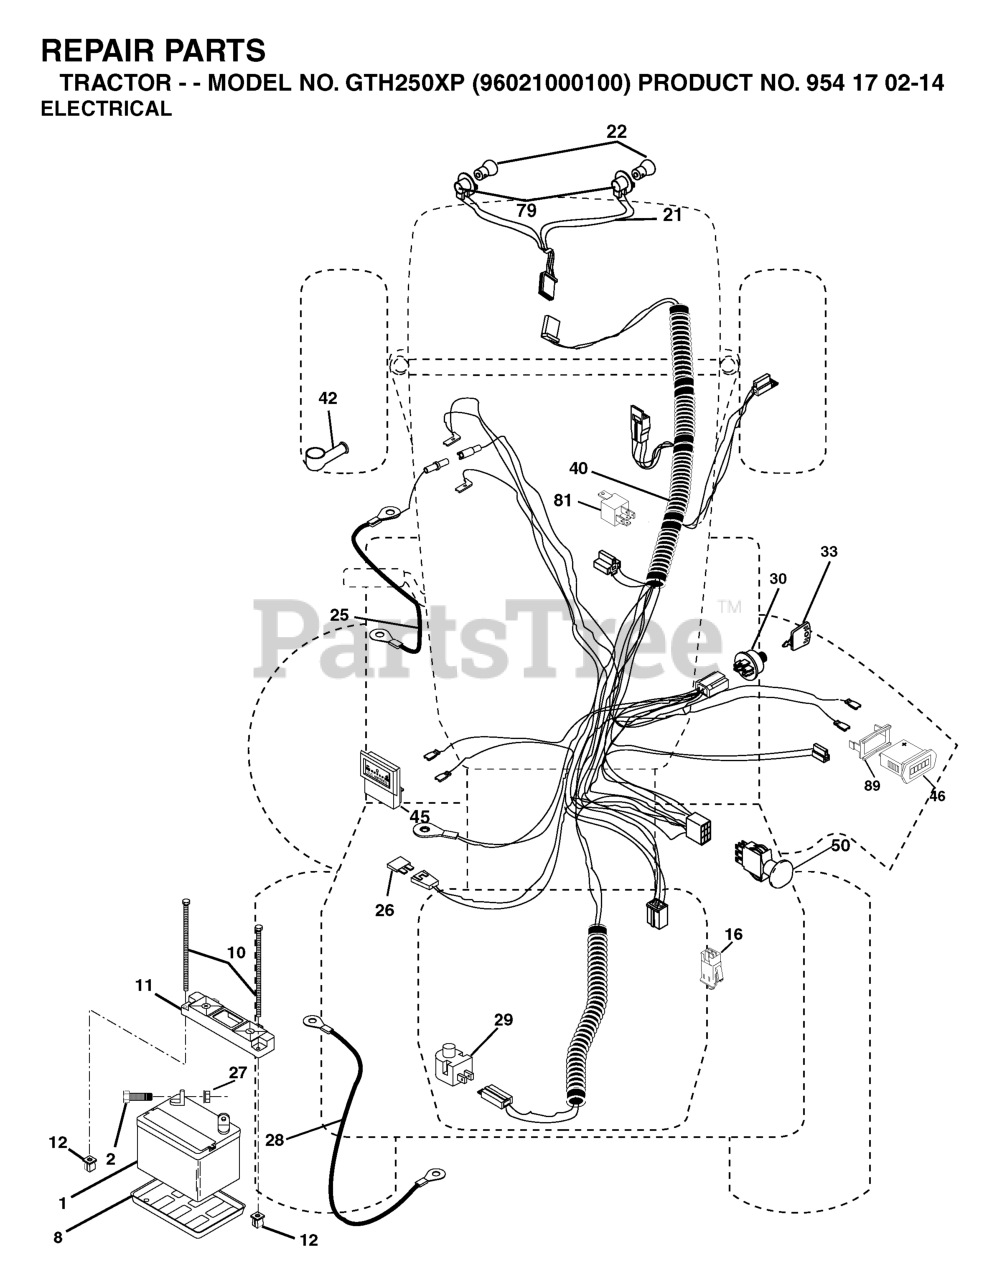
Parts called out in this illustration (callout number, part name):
1	BATTERY 12V .35 AMP
2	BOLT.HEX.1/4.X.3/4.DICHROMATE
8	BATTERY TRAY T
10	BOLT 1/4-20 X 7.5
11	BATTERY HOLDDOWN FRONT MOUNT
12	NUT, PUSH NYLON 1/4" BATTERY
16	SWITCH INTERLOOK PUSH-IN
21	HARNESS.W/LIGHT SOCKET
25	CABLE.4GA.RED.W/16GA.RED.WIRE
27	NUT
28	CABLE, GROUND
29	RP.SWITCH.PLUNGER.NC.GRAY
30	IGNITION SWITCH
33	KEY MLD GEN DELTA
42	COVER.TERMINAL.RED
46	HOUR METER
50	RP.PTO.SWITCH.8 TERMINAL.BLACK
79	BULB HOLDER ASM.
81	RELAY.ASSY.T
89	BRACKET SNAP-IN HOURMETER
